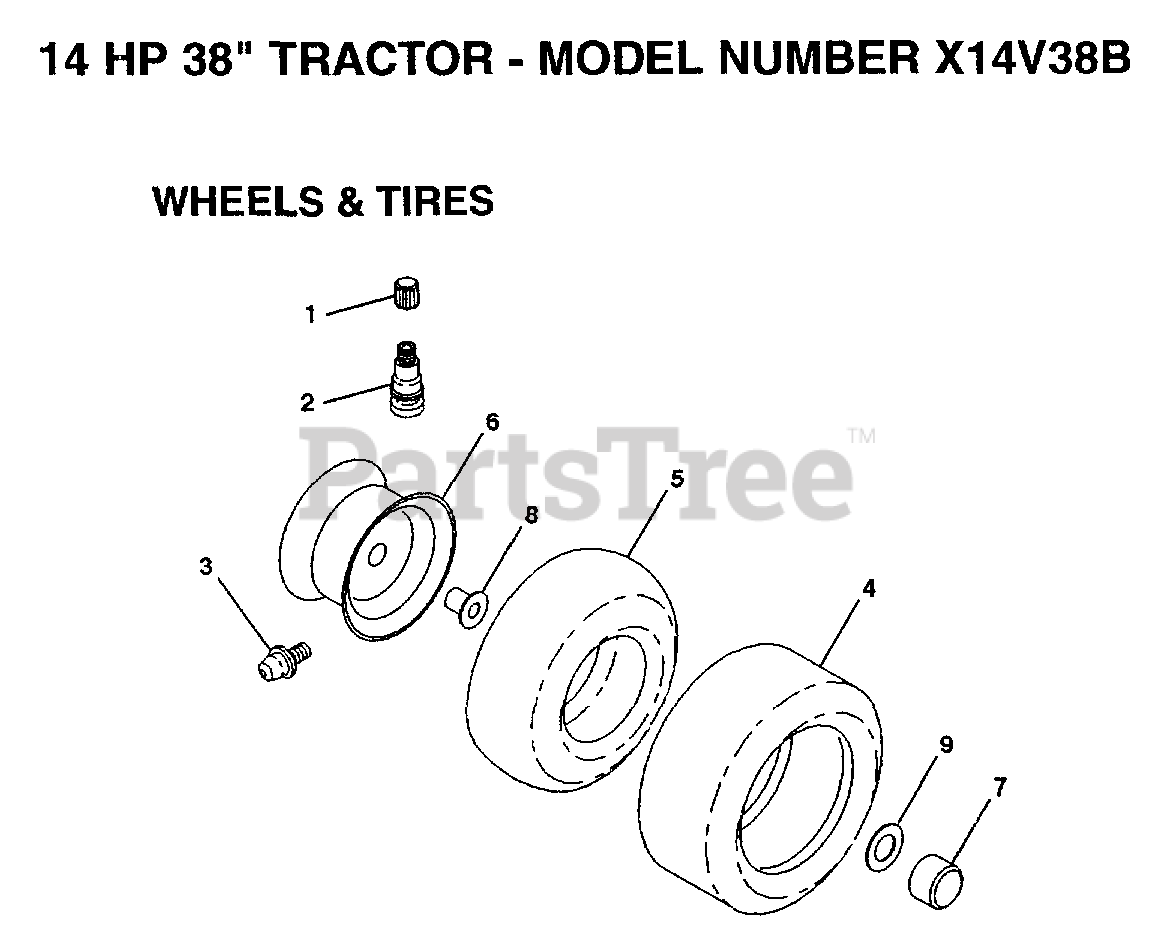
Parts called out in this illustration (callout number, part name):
1	VALVE CAP
3	FITTING LT
5	TUBE.18X9.5-8
5	TUBE.5.3/4.5/6
6	VALVE STEM LT
7	HUB CAP
8	"FLANGE, BEARING"
9	WASHER
